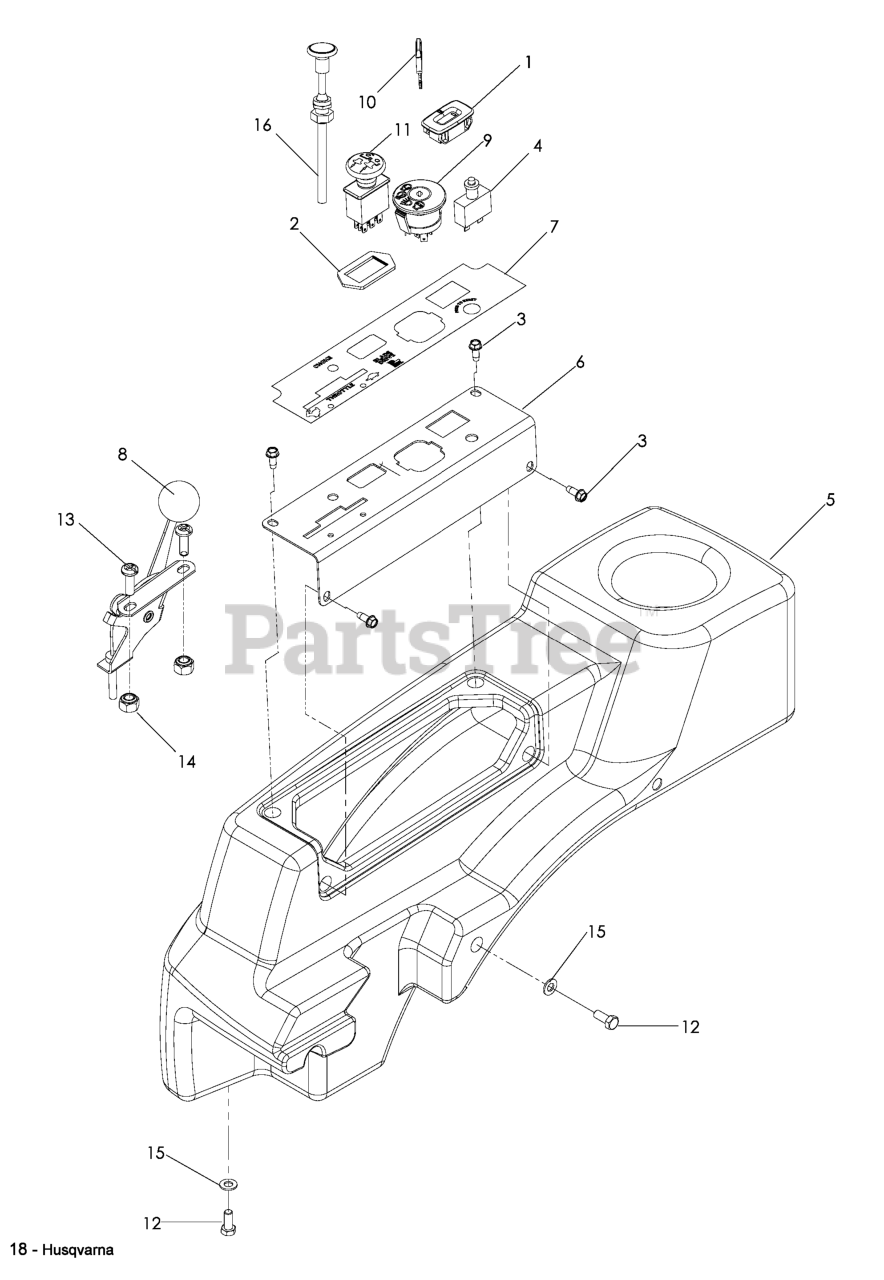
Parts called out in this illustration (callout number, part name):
1	HOUR METER
2	PTO SWITCH RETAINER
3	SCREW 1/4 X 5/8
4	CIRCUIT BREAKER W58XB1A4A15
5	FENDER, RT, HUSQ
6	CONTROL PANEL, BLACK
7	DECAL, CONTROL PANEL HUSQ
8	THROTTLE CABLE
9	RP IGNITION SWITCH
10	KEY
11	RP.SWITCH, BLADE
12	HCS 5/16C X 3/4
13	SCREW #10-24 X 5/8
14	NUT 10-24 NYLOC
15	FLAT WASHER 5/16 SAE
16	PUSH/PULL CHOKE CABLE
